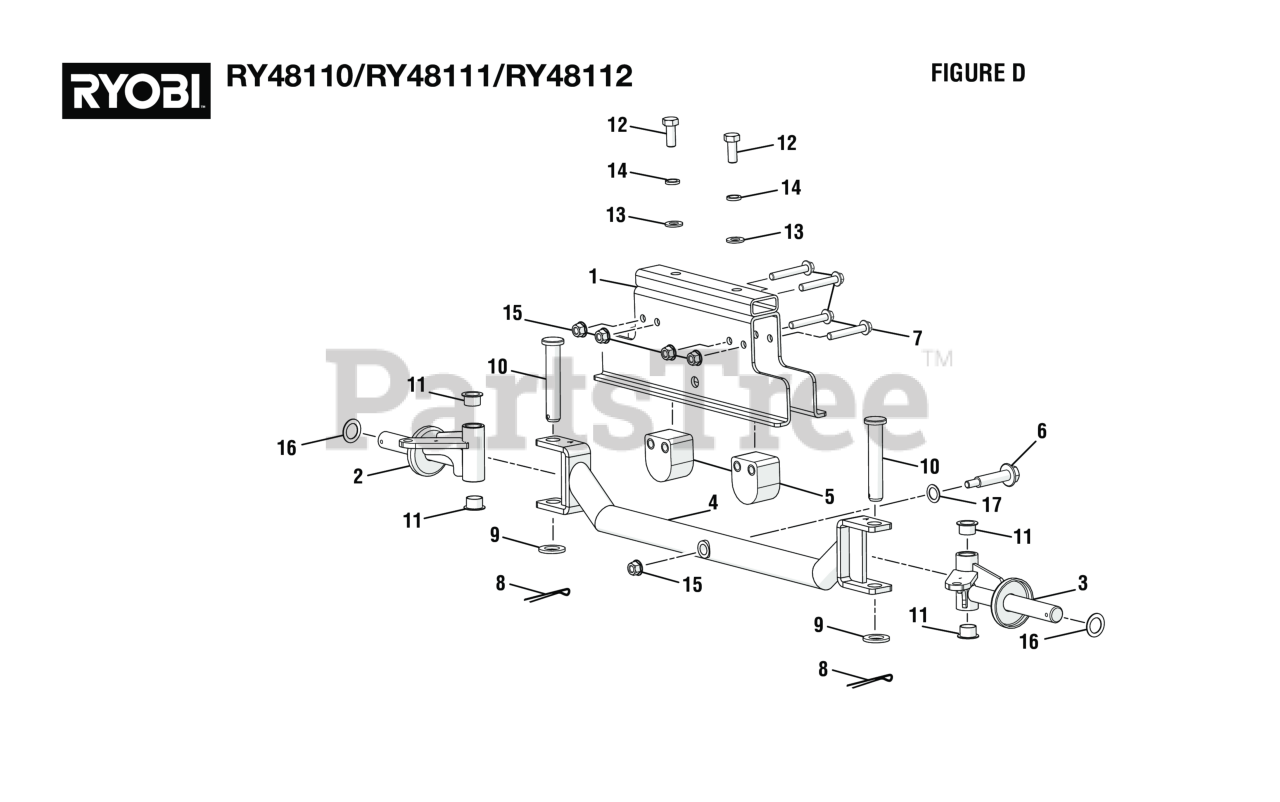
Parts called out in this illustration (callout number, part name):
1	Front Axle Channel Plate w/Brackets
2	Right Steering Knuckle
3	Left Steering Knuckle
4	Front Axle
5	Front Axle Rubber Bumper Assembly
6	Shoulder Bolt (M8 x 60 mm, Flange Hex Hd.)
7	Bolt (M8 x 55 mm, Flange Hex Hd.)
8	Cotter Pin (4 x 40 mm)
9	Washer (OD30 x ID17 x 3t)
10	Steering Knuckle Anchor
11	Steering Knuckle Bushing
12	Bolt (M10 x 45 mm, Hex Hd.)
13	Washer (OD20 x ID10.5 x 2t)
14	Lock Washer (M10)
15	Flange Nut (M8) (For Drive Motor Controller V)
16	Washer (OD28 x ID20.5 x 2t)
17	Washer (OD24 x ID13 x 2.5t)
